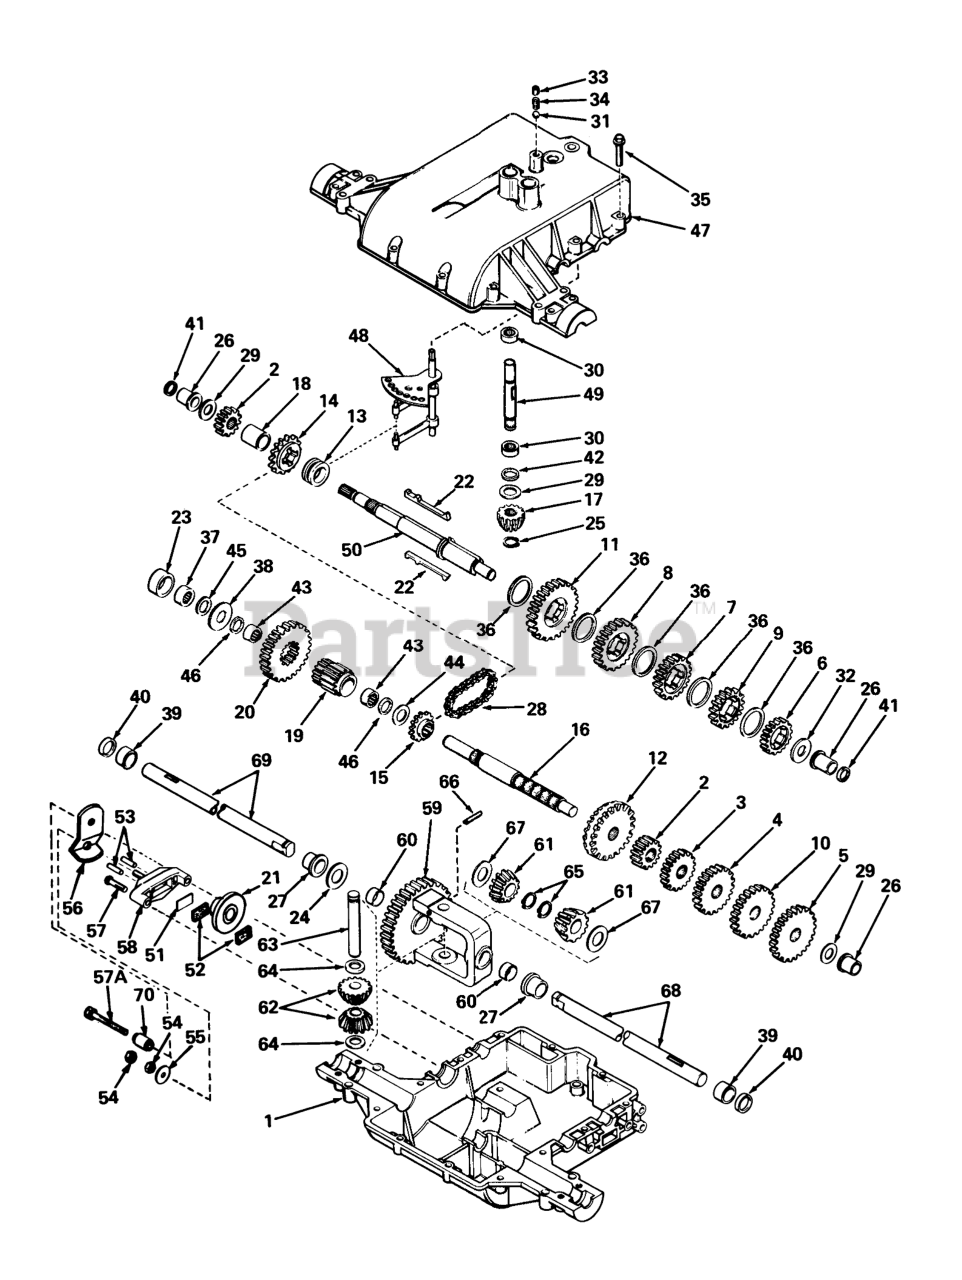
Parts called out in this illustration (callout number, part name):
1	Case, Transaxle
2	Gear-Spur 15 Teeth
3	Gear, Spur (20 teeth)
4	Gear, Spur (25 teeth)
5	Gear, Spur (30 teeth)
6	Gear-Spur 20 teeth
7	Gear, Spur (25 teeth)
8	Gear, Spur (30 teeth)
9	ASpur Gear (22 Teeth)
10	Gear, Spur (28 teeth)
11	Gear-Spur, 35 Teeth
12	Gear, Bevel (42 teeth)
13	Collar-Shift
14	Sprocket (14 Teeth)
15	Sprocket 10t
16	Shaft-Counter
17	Bevel Pinion, Input
18	Spacer
19	Pinion-Output
20	Gear-Output
23	Spacer
24	Washer
25	Ring-Retainer
26	Bushing, Flanged
27	Bronze Bearing
28	Chain, Roller (#41 Chain, 22 Links)
29	Washer
30	Bearing-Needle
31	Ball-Steel
32	Washer
33	Screw-Set
34	Spring
35	Ring Set (.020 O S)
36	Washer
37	Bearing-Needle
38	Washer-Flat
39	Bearing-Cartridge
40	Seal Oil
41	Ring-Square Cut
42	O Ring
43	Bearing-Needle
44	Washer-Flat
45	Ring-Square Cut
46	Ring-Square Cut
47	Cover, Transaxle
48	Rod & Fork Assembly
49	Shaft, Input
50	Shaft, Brake
51	Brake Pad Plate
52	Brake Pad
53	Dowel Pin
54	Locknut
55	Washer
56	Lever-Brake
57	Ring Set (.020 O S)
57A	Screw-Hex. Flange
58	Holder-Brake Pad
59	Gear Assembly, Differential (Incl. 2 of No. 60)
60	Bushing
61	Bevel Gear
62	Gear Pinion
63	Drive Pin
64	Thrust Washer
65	Snap Ring
66	Pin-Roll
67	Washer
68	Axle (14-7/8" long)
69	Axle (13" Long)
70	Spacer
